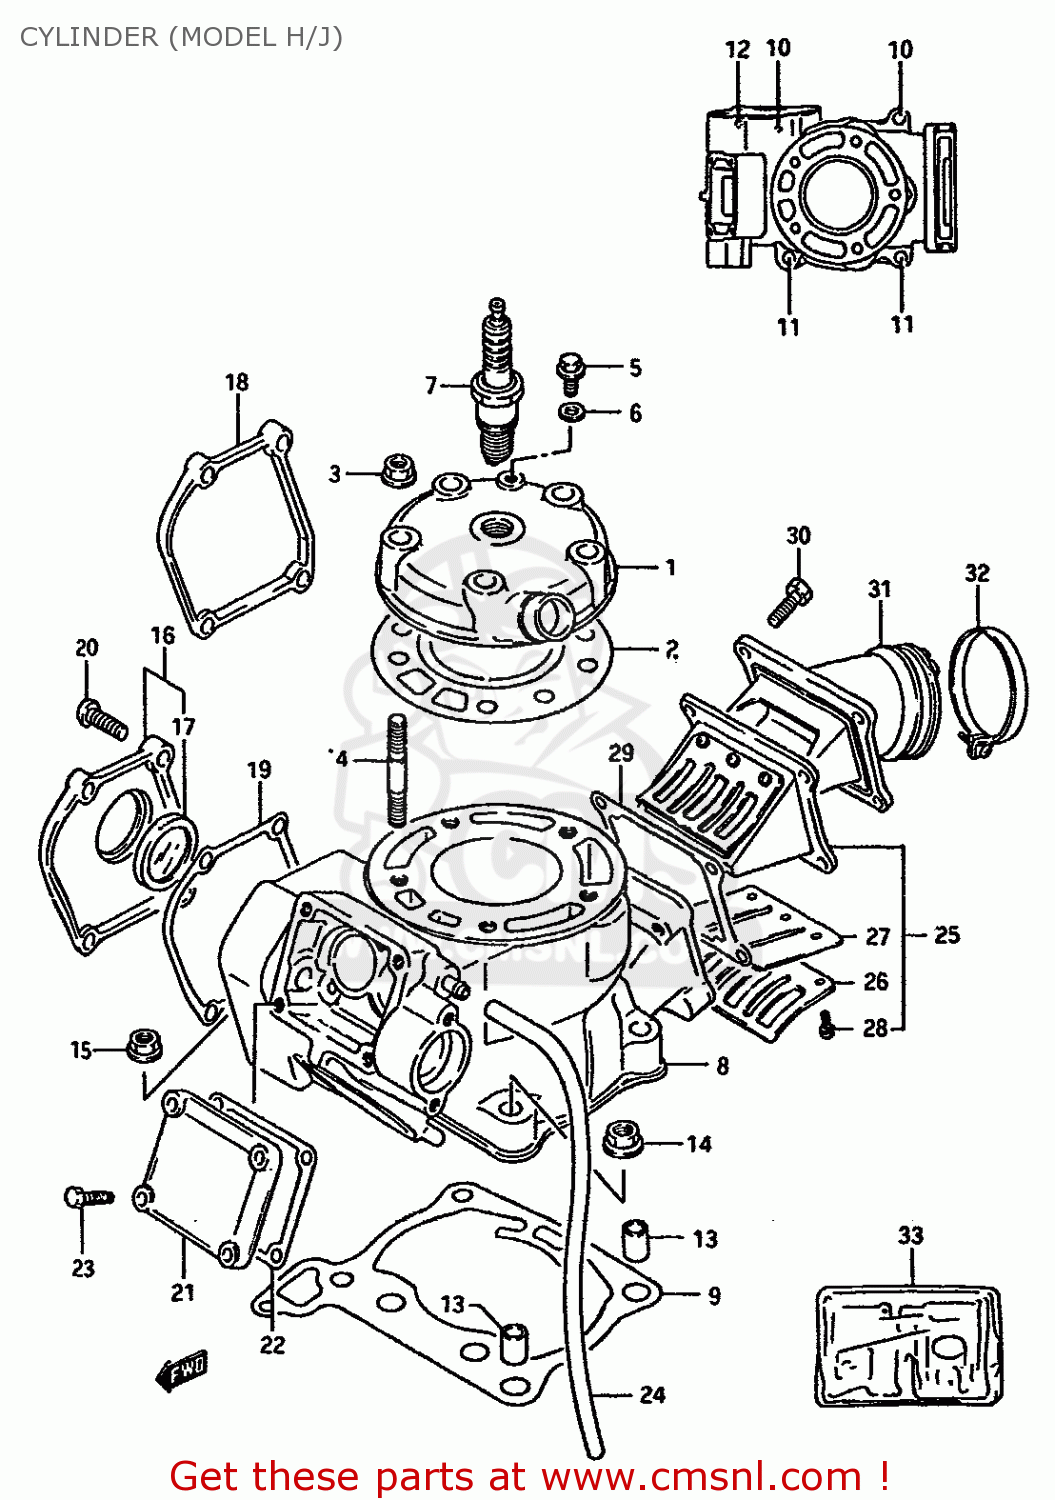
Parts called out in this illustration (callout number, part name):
1	HEAD,CYLINDER
2	GASKET,CYLINDER HEAD
3	NUT
4	BOLT,STUD
5	UNION
6	GASKET(6.2X11X1).2 (NAS)
7	SPARK PLUG
8	CYLINDER
9	GASKET,CYLINDER
10	STUD
11	BOLT,STUD
12	STUD
13	PIN
14	NUT
15	NUT
16	COVER,CYLINDER NO. 1
17	LENS
18	COVER,CYLINDER NO. 1
19	GASKET,CYLINDER COVER NO. 1
20	SCREW
21	COVER,CYLINDER NO. 2
22	GASKET,CYLINDER COVER NO. 2
23	BOLT
24	HOSE
25	VALVE ASSY, REED
26	STOPPER
27	VALVE,REED
28	SCREW,REED VALVE
29	GASKET,REED VALVE
30	BOLT
31	PIPE,INTAKE
32	CLAMP
33	GASKET SET (MCA)
